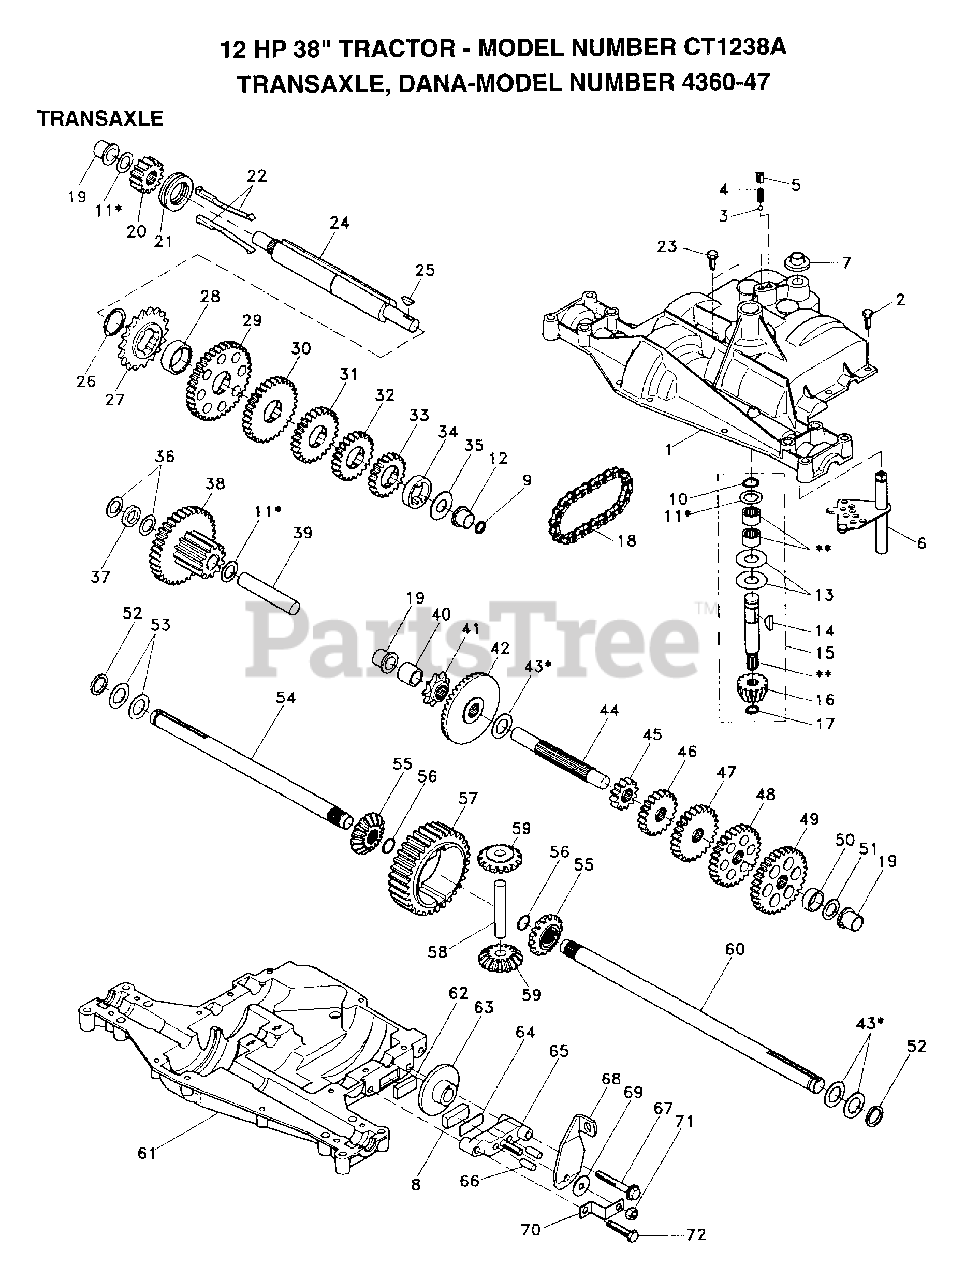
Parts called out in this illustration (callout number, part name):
1	HOUSING UPPER
3	BALL, DETENT
4	SPRING, DETENT
5	SCREW, SET
6	SHIFTER ASSEMBLY
7	BOOT, SHIFTER
8	PUCK, FRICTION
9	SQUARE RING
10	RING RETAINING
11	ASSY, KIT, SHIM .625 SHAFT
12	BEARING FL
13	WASHER, PLAIN .632 X 1.38 X .046
14	KEY WOODRUFF #9
15	ASSEMBLY, KIT, INPUT SHAFT
16	PINION, BEVEL, 14 TEETH
17	RING, RETAINING
18	CHAIN, 24 PITCHES
19	BEARING, FLANGE
21	COLLAR, CLUTCH
22	ASSEMBLY, KIT, CLUTCH KEYS
23	SCREW TAPPING WITH SEALER
24	SHAFT INTERMEDIATE
25	KEY, WOODRUFF, #61
26	RING, RETAINING
27	SPROCKET, 18 TEETH
29	GEAR, SPUR, 37 TEETH
30	GEAR, SPUR, 30 TEETH
31	GEAR, SPUR, 25 TEETH
32	GEAR, SPUR, 22 TEETH
33	GEAR, SPUR, 19 TEETH
35	WASHER, PLAIN .640 X 1.37 X .061
36	WASHER, PLAIN .632 X 1.00 X .026
37	SPACER .630 X 1.00 X .169
38	ASSY GEAR COMB 12&35 TEETH
39	SHAFT, IDLER
40	SPACER .635 X .875 X .755
41	SPROCKET, 9 TEETH
42	GEAR, BEVEL, 42 TEETH
43	ASSY, KIT, SHIM .750 SHAFT
44	SHAFT, DRIVE
45	GEAR, SPUR, 12 TEETH
46	GEAR, SPUR, 20 TEETH
47	GEAR, SPUR, 25 TEETH
48	GEAR, SPUR, 28 TEETH
49	GEAR, SPUR, 31 TEETH
51	WASHER, PLAIN .632 X 1.00 X .060
52	WASHER, NEOPRENE
53	WASHER, PLAIN .758 X 1.25 X .031
54	AXLE LEFT HAND
55	GEAR, MITER, 15 TEETH
56	RING, RETAINING
57	GEAR, SPUR, 32 TEETH
58	SHAFT, CROSS
59	GEAR, MITER, 15 TEETH
60	AXLE, R.H.
61	HOUSING LOWER
62	PUCK, FRICTION
63	DISC, BRAKE
65	JAW, BRAKE
66	PIN, DOWEL
67	SCREW, SELF-TAPPING
68	LEVER ACTUATING
69	WASHER, PLAIN .321 X 1.00 X .055
70	BRACKET, ANTI-ROTATION
71	LOCKNUT 5/16-24
72	SCREW TAPPING
